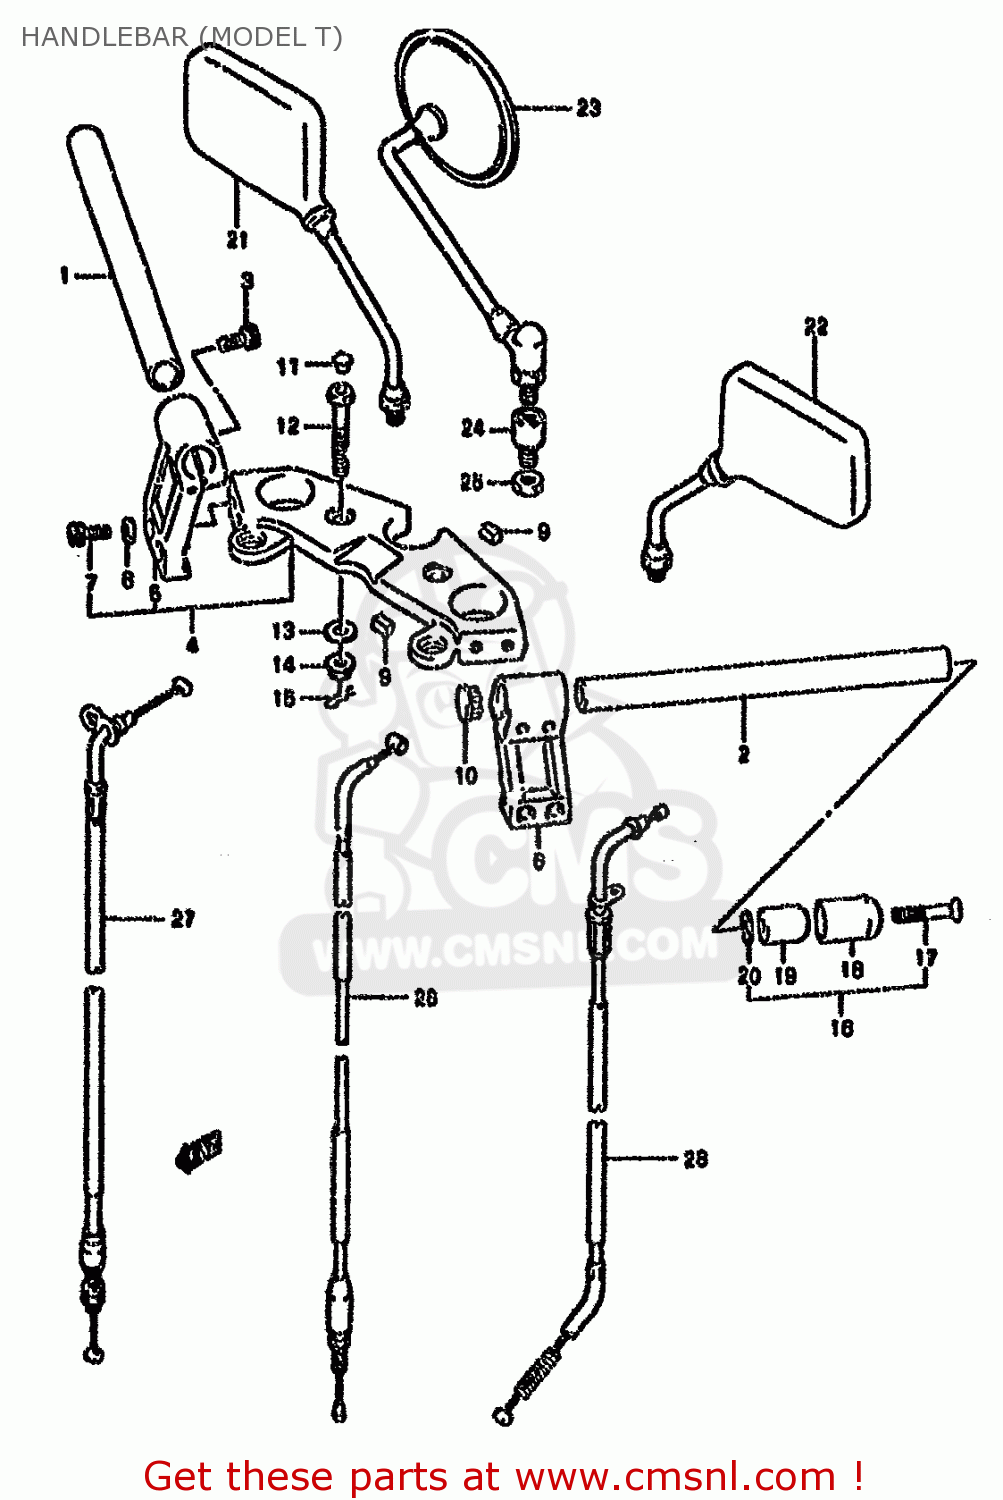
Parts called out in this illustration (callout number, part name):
1	HANDLEBAR,R
2	HANDLEBAR,L
3	BOLT,CL.COVER
4	HOLDER ASSY,HANDLEBAR
5	HOLDER,HANDLEBAR,R(SILVER)
6	HOLDER,HANDLEBAR,L(SILVER)
7	BOLT
8	WASHER
9	CUSHION,HANDLE HOLDER
10	CAP,HANDLEBAR
11	CAP(OD:11)
12	BOLT(10X66)
13	WASHER(10.5X30X3.2)
14	NUT
15	PIN 20X20
16	BALANCER SET,HANDLEBAR
17	SCREW
18	CAP,HANDLE BALANCER
19	BALANCER,HANDLEBAR
20	SPACER,BALANCER
21	MIRROR ASSY,RE
22	MIRROR ASSY,LH
23	MIRROR ASSY,RH
24	CUSHION,REAR VIEW MIRROR
25	NUT
26	CABLE ASSY,CLUTCH
27	CABLE ASSY,THROTTLE
28	CABLE COMP,STARTER
